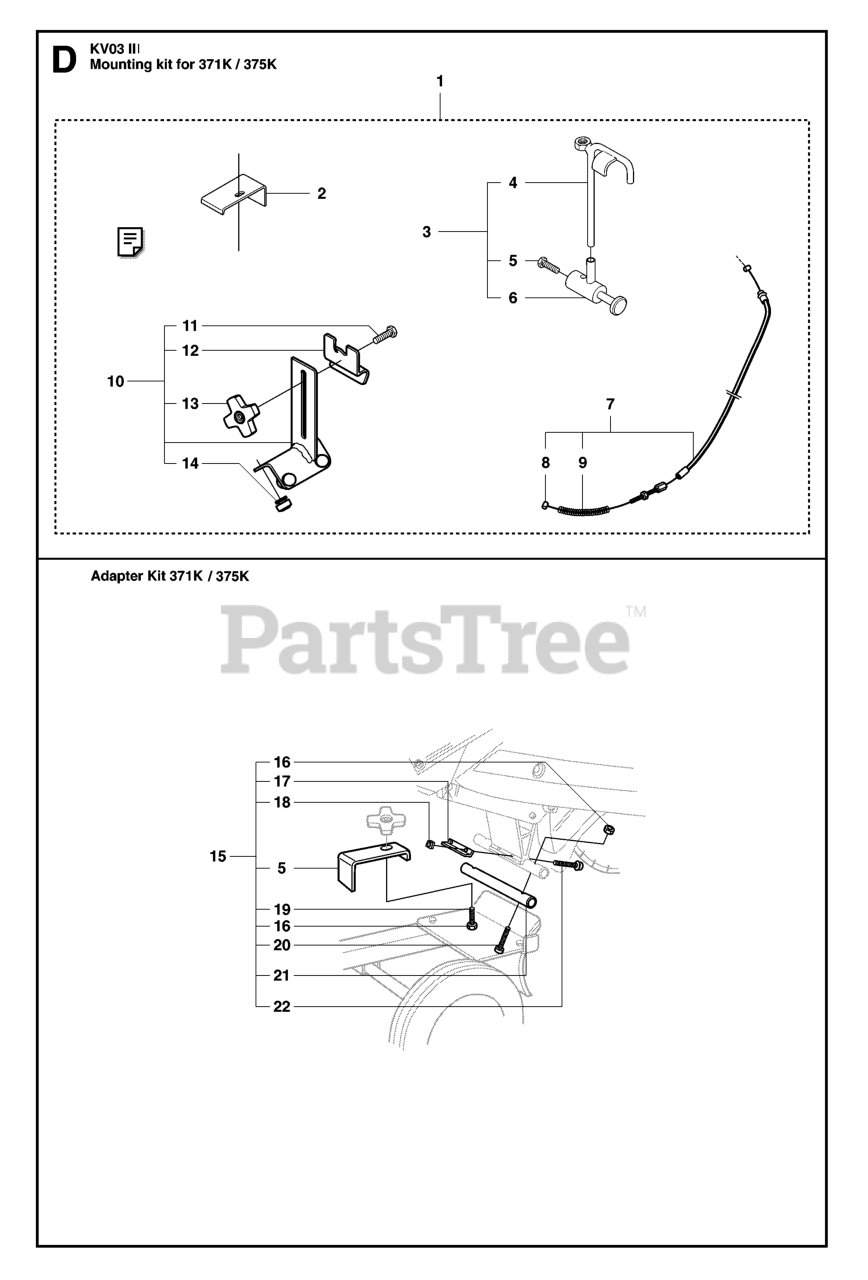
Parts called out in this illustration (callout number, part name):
1	ASSEMBLY KIT
3	THROTTLE TRIGGER COMPLETE
5	Slotted Truss Head Screw #10-32 x 5/8"
7	CABLE ASSY.
8	Cable Retainer
11	SCREW 8X20
15	BRACKET
16	NUT
18	LOCKNUT M5
22	SCREW MC6S 5X16
